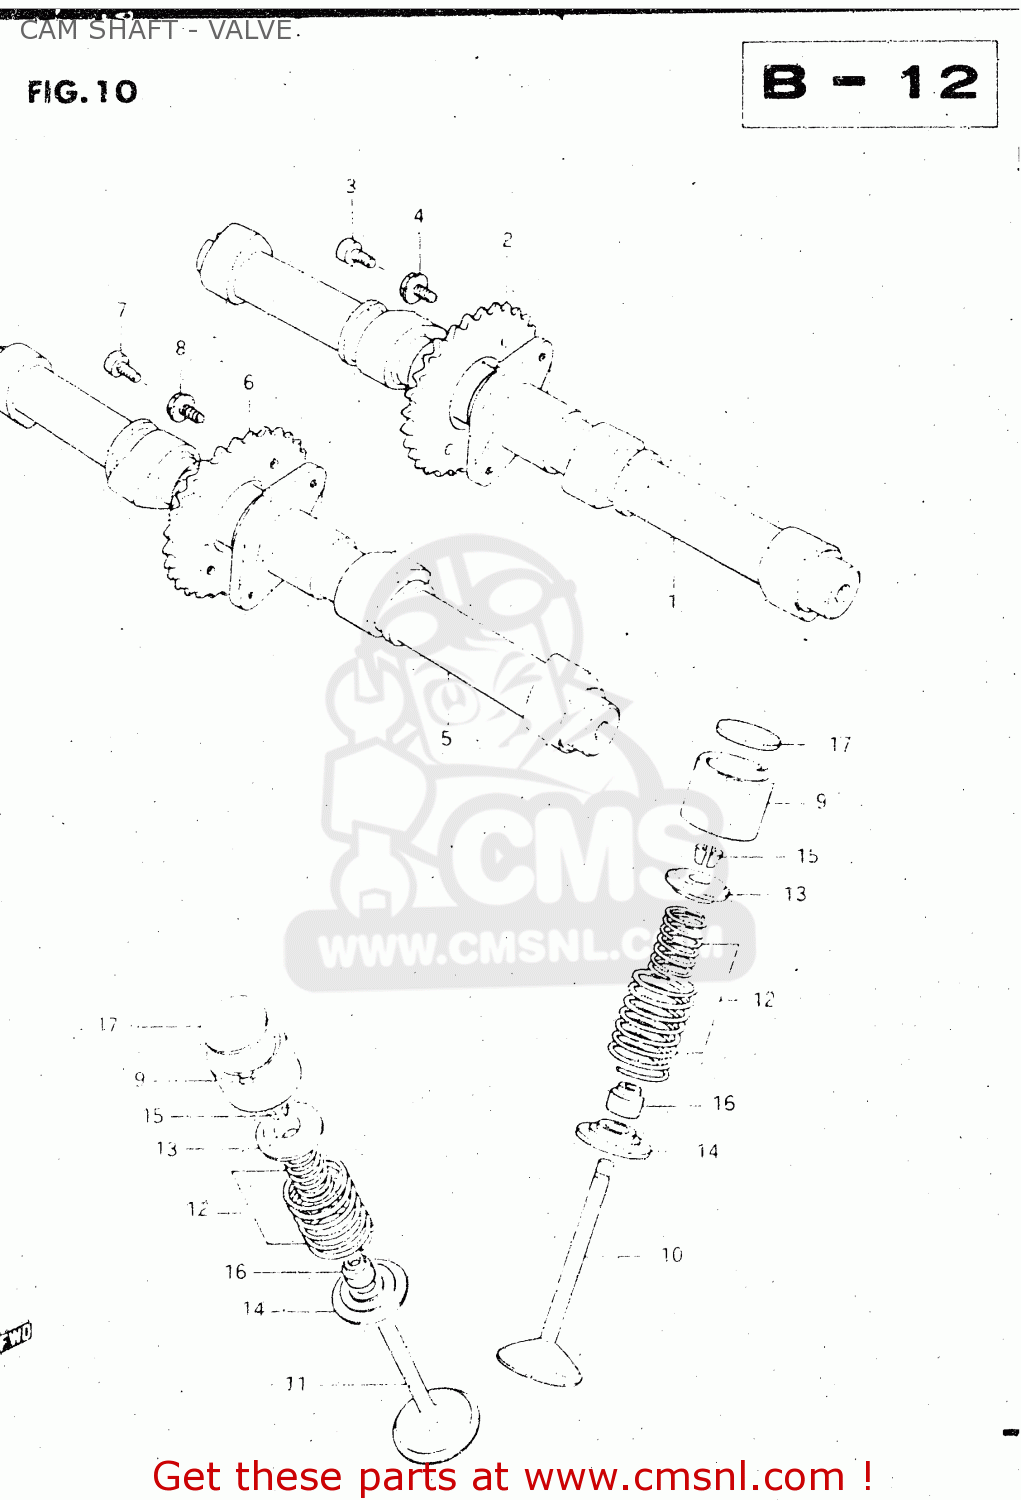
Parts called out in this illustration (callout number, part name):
1	CAMSHAFT
2	SPROCKET,CAMSHAFT
3	BOLT 6X11
4	BOLT(7X11)
5	CAMSHAFT,EXHAUST
6	SPROCKET,EXHAUST CAMSHAFT
7	BOLT 6X11
8	BOLT(7X11)
9	TAPPET
10	VALVE, INTAKE
11	VALVE, EXHAUST
12	SHIM,TAPPET
13	RETAINER,VALVE SPRING
14	SEAT,VALVE SPRING
15	COTTER VALVE
16	SEAL,OIL(7X14.4X9)
17	SHIM,TAPPET
